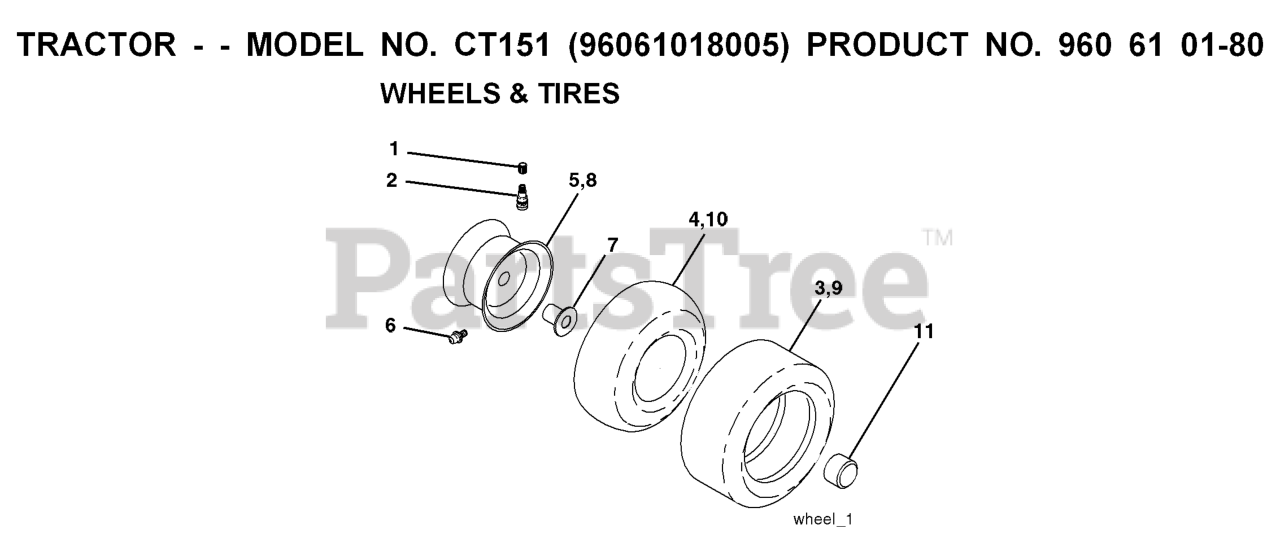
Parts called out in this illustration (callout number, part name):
2	VALVE STEM LT
3	TIRE HEAVY DUTY
4	TUBE.5.3/4.5/6
5	RIM ASM 6" FRONT SILVER
6	FITTING LT
7	BEARING T
8	RIM ASM 8" REAR SILVER
9	TIRE HEAVY DUTY
10	TUBE
11	CAP, AXLE BLK
